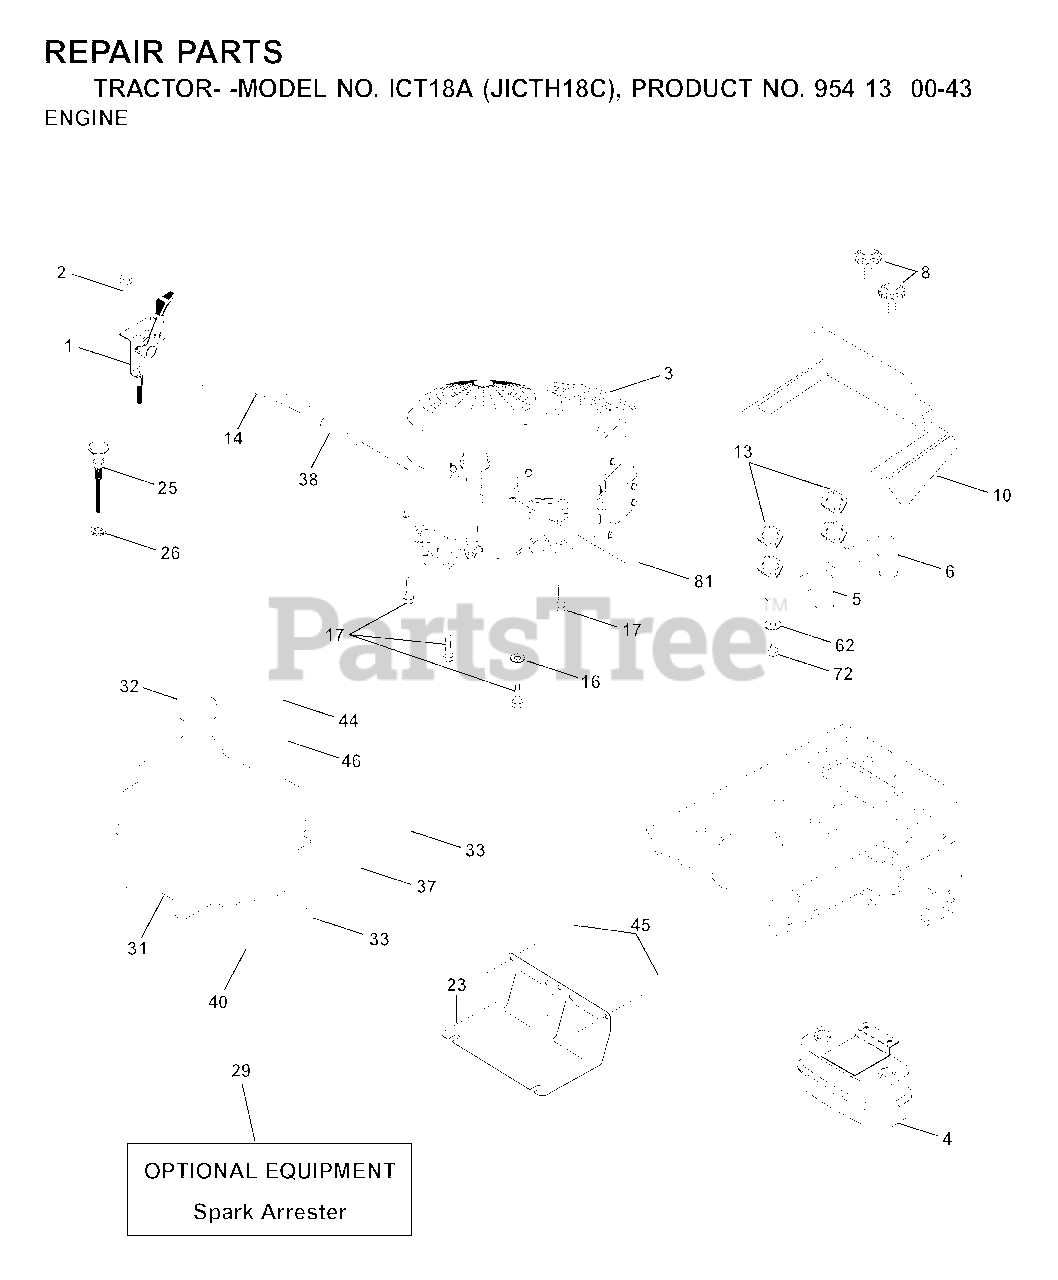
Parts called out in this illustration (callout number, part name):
1	CONTROL, THROTTLE
2	SCREW LT
4	MUFFLER.TWIN.CYL.LOW.TONE
5	TUBE MANIFOLD LH
6	EXHAUST TUBE RH
8	BOLT, 5/16-18 X 1 3/4
10	SHIELD.BROWNING.B&S
13	GASKET.MUFFLER
14	TUBE, DRAIN OIL ASM.
16	LOCKWASHER
17	SCREW LT
23	SHEILD.BROWNING.DBR.GUARD
25	CONTROL, CHOKE
26	NUT KEPS 3/8 - 24 UNF
29	ARRESTER SPARK (OPTIONAL)
31	TANK, 2GAL
32	FUEL CAP
33	HOSE CLAMP
37	LINE.FUEL.20
38	PLUG, OIL DRAIN EASY
40	GROMMET T
44	SCREW HEXWSHR 1/4-20X3/4
45	SCREW, 3/8-16X3/4
62	LOCKWASHER
72	SCREW
81	NUT
